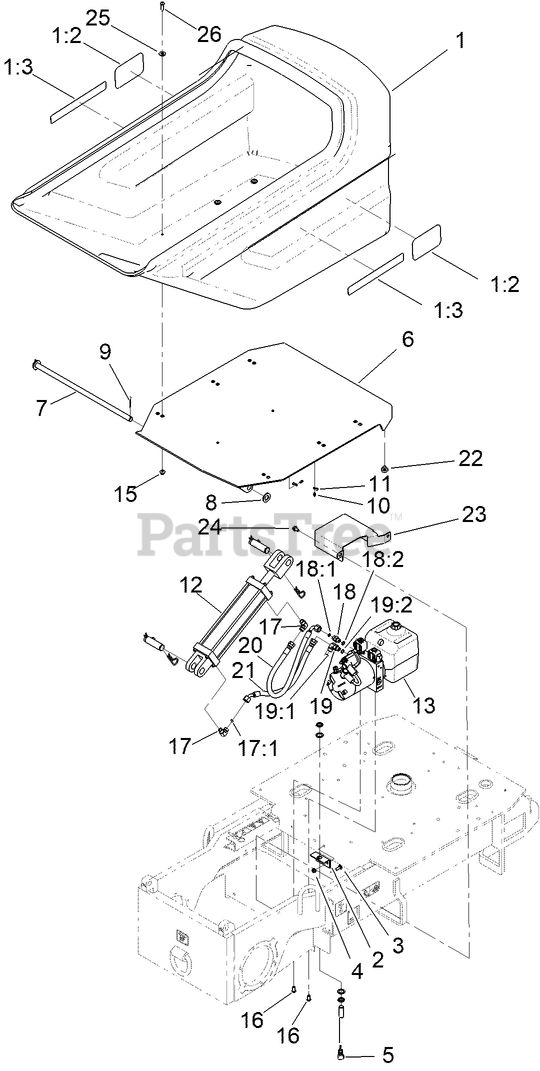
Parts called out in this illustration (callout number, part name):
1	MORTAR HOPPER ASM
1:3	DECAL - E-MUD BUGGY
2	BRACKET-SWITCH
3	BOLT-CARR
4	NUT-HF, NI
5	SENSOR-PROXIMITY, N.O.
6	DUMP BIN FRAME ASM-WELDED
7	SHAFT-DUMP PIVOT
8	WASHER-FLAT
9	PIN-COTTER
10	FITTING-GREASE
11	CAP-PLUG
12	HYD CYLINDER ASM
13	PUMP UNIT-48 VDC
15	NUT-HF, NI
16	SCREW-HH
17	FITTING-ELBOW, 90
17:1	O-RING
18	FITTING-STRAIGHT
18:1	O-RING
18:2	O-RING
19	FITTING-ELBOW, 90 DEG
19:1	O-RING
19:2	O-RING
20	HOSE ASM-HYD
21	HOSE ASM-HYD
22	BUMPER-RUBBER
23	COVER-CONTACTOR
24	SCREW-HWHTF
25	WASHER-FLAT
26	SCREW-HSBH
